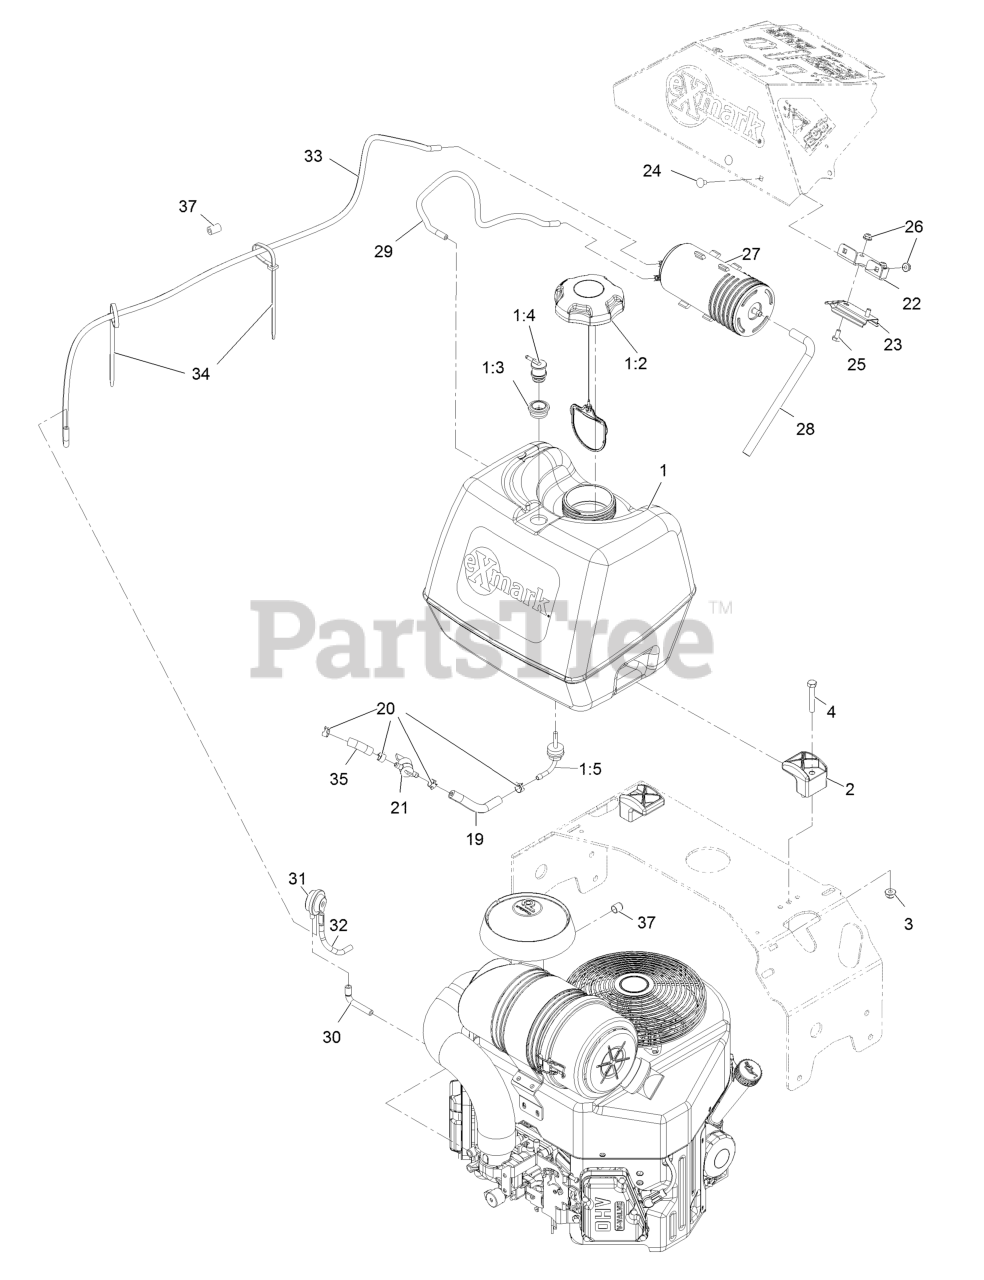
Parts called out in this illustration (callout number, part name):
1	ASM, FUEL TANK
1:3	GROMMET
1:4	VALVE-VENT, FUEL
1:5	FITTING-FUEL, BULKHEAD
3	NUT-HF, NI
4	SCREW-HH
19	HOSE-FUEL
20	CLAMP-HOSE
21	VALVE-FUEL
22	BRACKET-CANISTER, CARBON
23	BRACKET-CANISTER, CARBON
24	SCREW-CARR
25	SCREW-HH
27	CANISTER-CARBON, 800CC
28	HOSE-VENT, CANISTER
29	HOSE-VENT
30	HOSE-VENT, FORMED
31	VALVE-CONTROL, VACUUM
32	HOSE-VENT, FORMED
33	HOSE-VENT, FORMED
34	TIE-PLASTIC
35	HOSE-FUEL
37	PLUG-PORT
